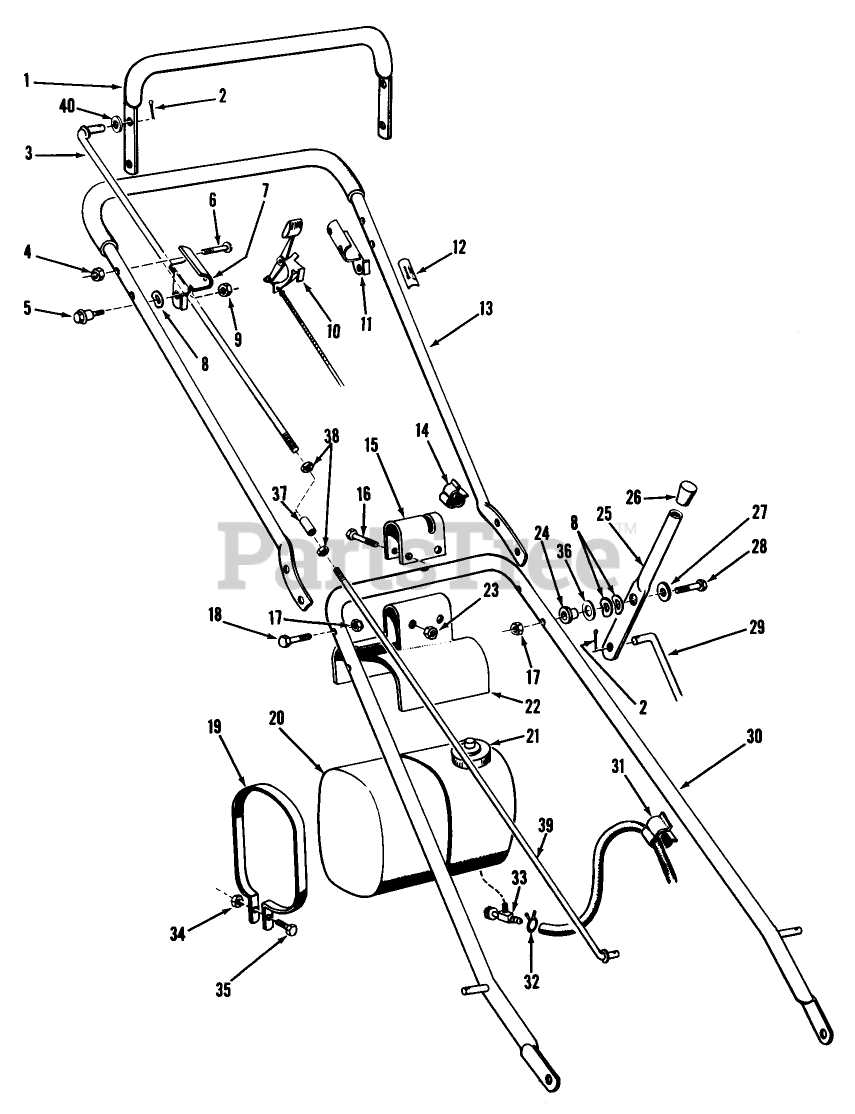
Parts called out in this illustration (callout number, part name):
2	PIN-COTTER
4	NUT-LOCK, NI
8	WASHER-SPRING
9	NUT-LOCK, NI
12	Decal
14	Clamp
16	SCREW-HH
17	NUT-KEPS
18	SCREW-HH
23	NUT-LOCK, NI
25	Cutter Handle
26	Plug Button
27	WASHER-FLAT
28	SCREW-HH
29	Cutter Rod 25"
34	NUT-LOCK, NI
35	SCREW-HH
36	WASHER-FLAT
38	NUT-KEPS
